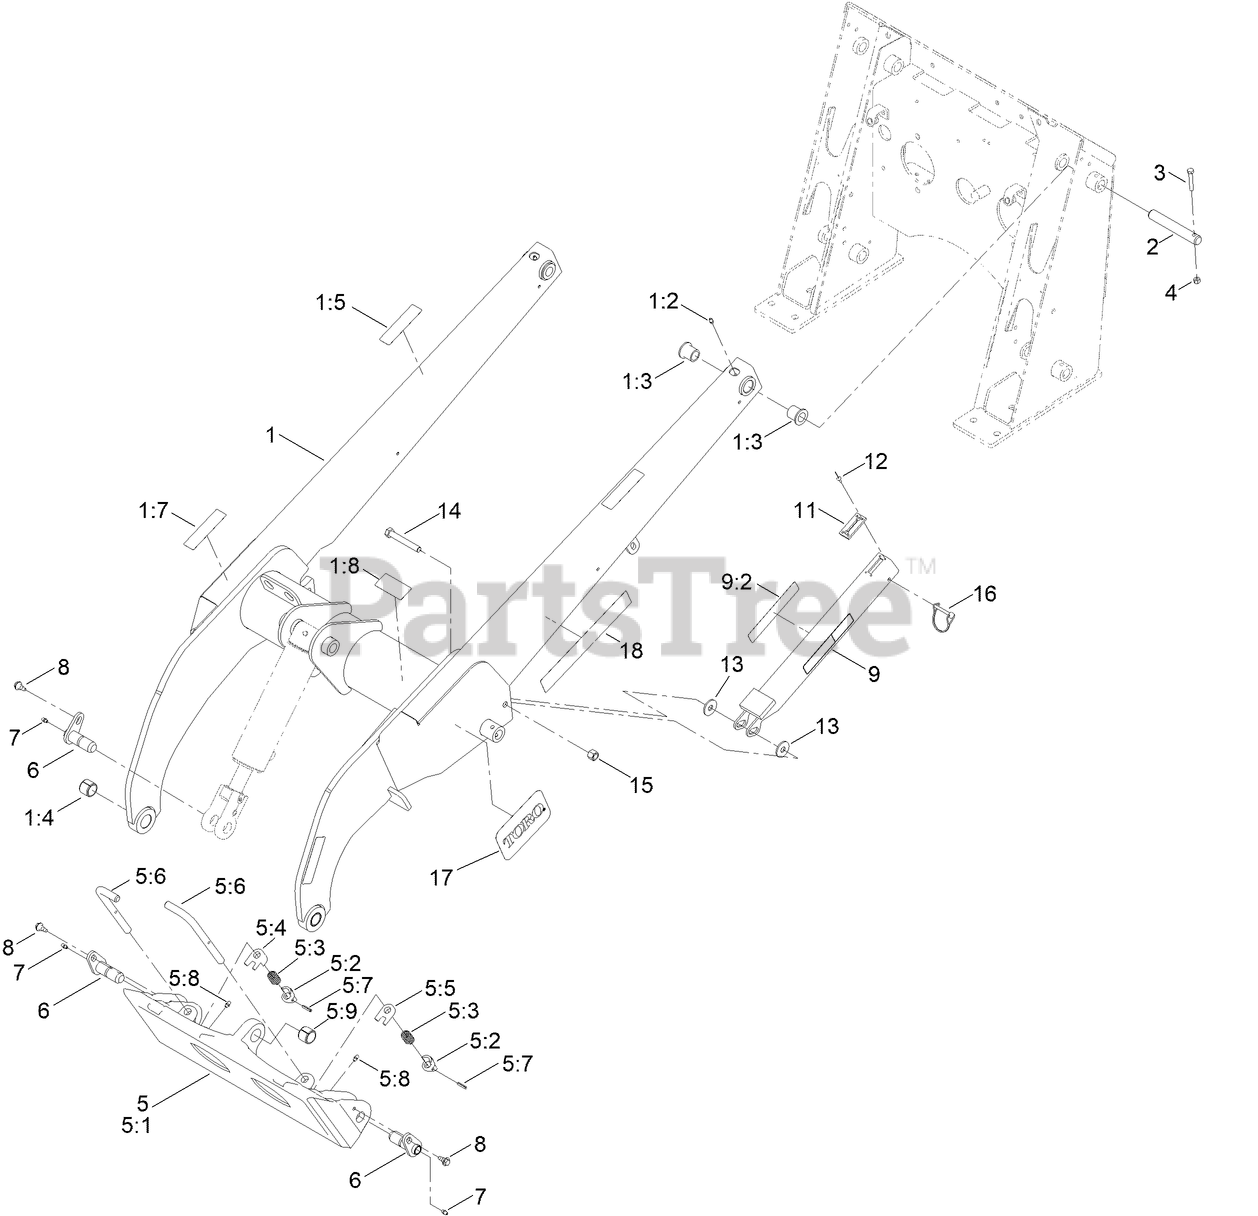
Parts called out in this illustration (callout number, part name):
1	LOADER ARM ASM
1:2	FITTING-GREASE
1:3	BUSHING
1:4	BUSHING-TENSION
1:5	DECAL-WARNING, PINCH
1:7	DECAL-CAUTION
1:8	DECAL-NO RIDER
2	PIN-LOCKING
3	SCREW-HH
4	NUT-LOCK, NI
5	QUICK ATTACH ASM
5:1	MOUNT-QTACH
5:3	SPRING-COMPRESSION
5:4	STOP-RH
5:5	STOP-LH
5:6	PIN-LOCKING
5:7	PIN-GROOVED
5:8	FITTING-GREASE
5:9	BUSHING-TENSION
6	PIN-PIVOT
7	FITTING-GREASE
8	BOLT-SHOULDER
9	LOCKING ARM ASM
9:2	DECAL-DANGER
11	STOP-RUBBER
12	RIVET
13	WASHER-RUBBER
14	SCREW-HH
15	NUT-LOCK, NI
16	PIN-HITCH
